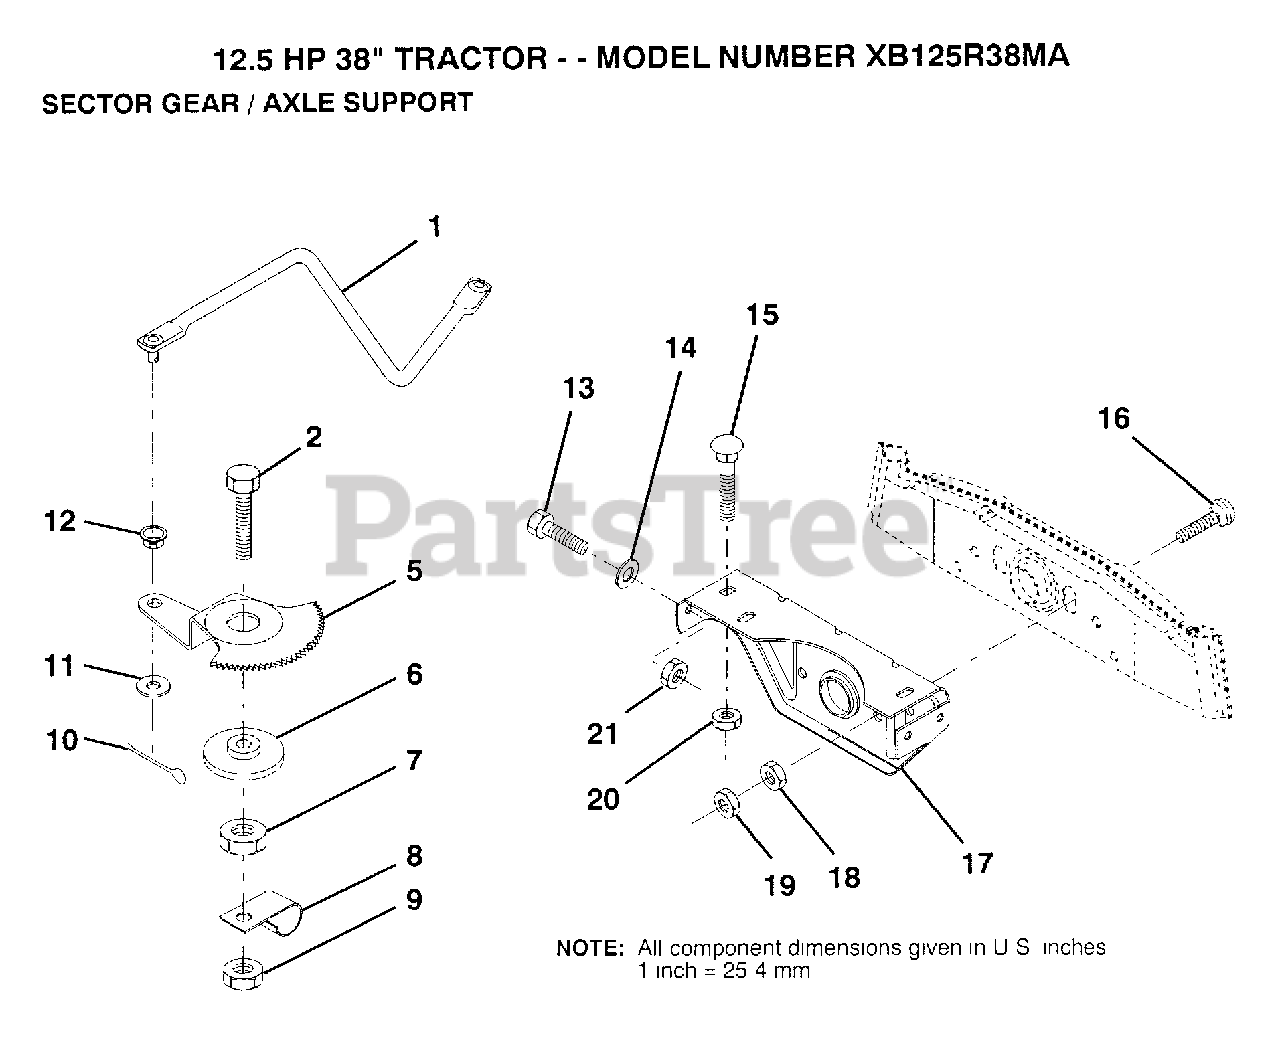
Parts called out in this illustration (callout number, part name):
1	DRAG LINK
2	"BOLT,HEX"
5	GEAR SECTOR
6	BUSHING
7	NUT
8	CLIP INSULATOR
9	NUT LTV
10	COTTER PIN
11	WASHER
12	BUSHING.DRAGLINK
13	BOLT
14	WASHER
15	BOLT
16	BOLT
17	"SUPT,FRT AXLE"
18	NUT.HEX.3/8-16UNC
19	LOCKNUT
